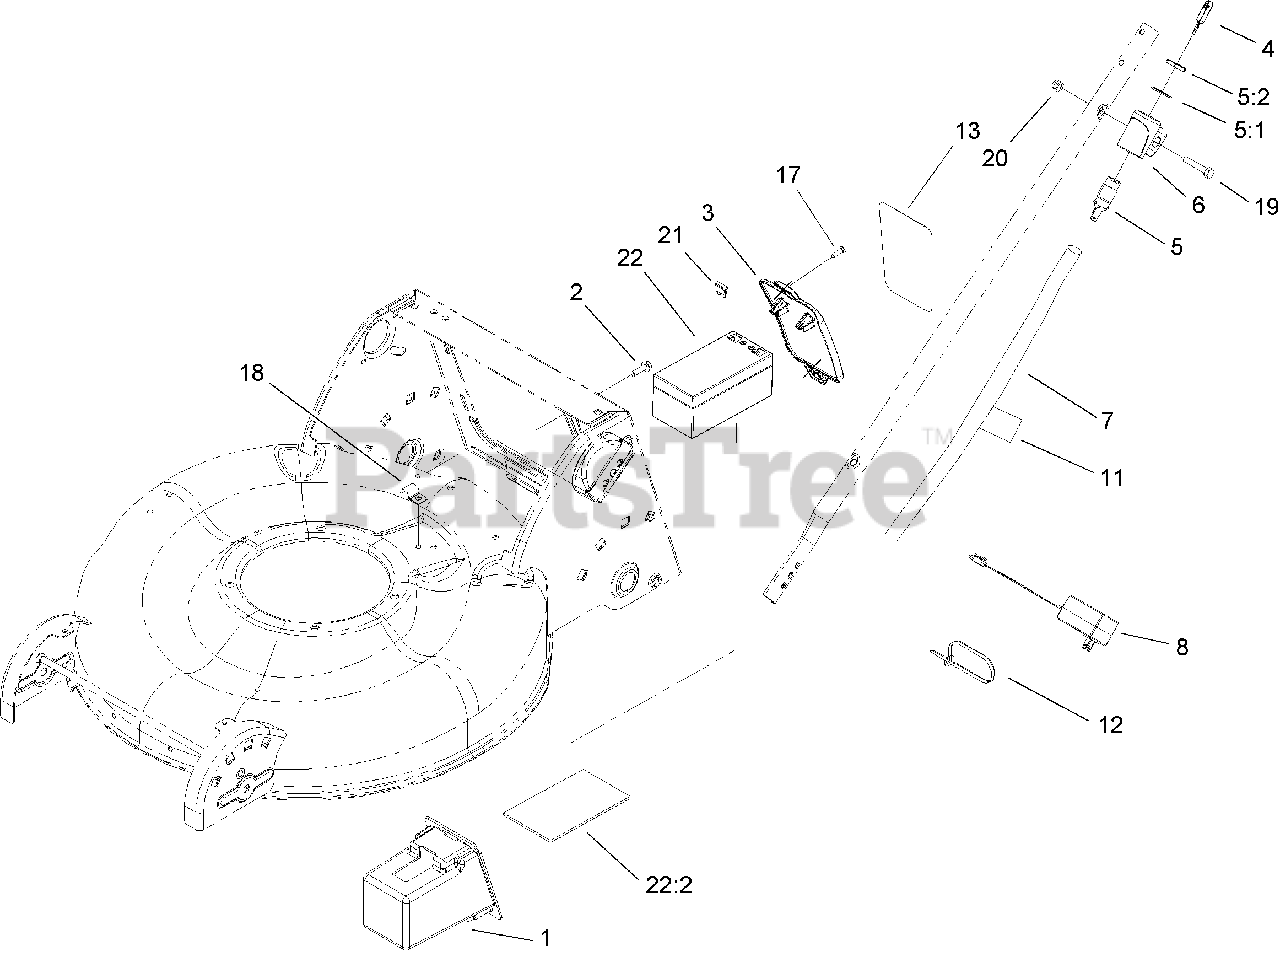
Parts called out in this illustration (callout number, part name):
1	BOX-BATTERY
2	SCREW-HWH
3	COVER-BATTERY
5	SWITCH-STARTER
5:1	WASHER-TOOTH
6	Mount-Switch
7	HARNESS-WIRE
8	CHARGER-12 VOLT
11	DECAL-HARNESS
12	STRAP-TIE
13	DECAL-INSTRUCTION, BATTERY
17	SCREW-PPH
18	CLIP-HALF
19	SCREW-HH
20	NUT-LOCK, NI
21	FUSE-40 AMP
22:2	FOAM-BATTERY
